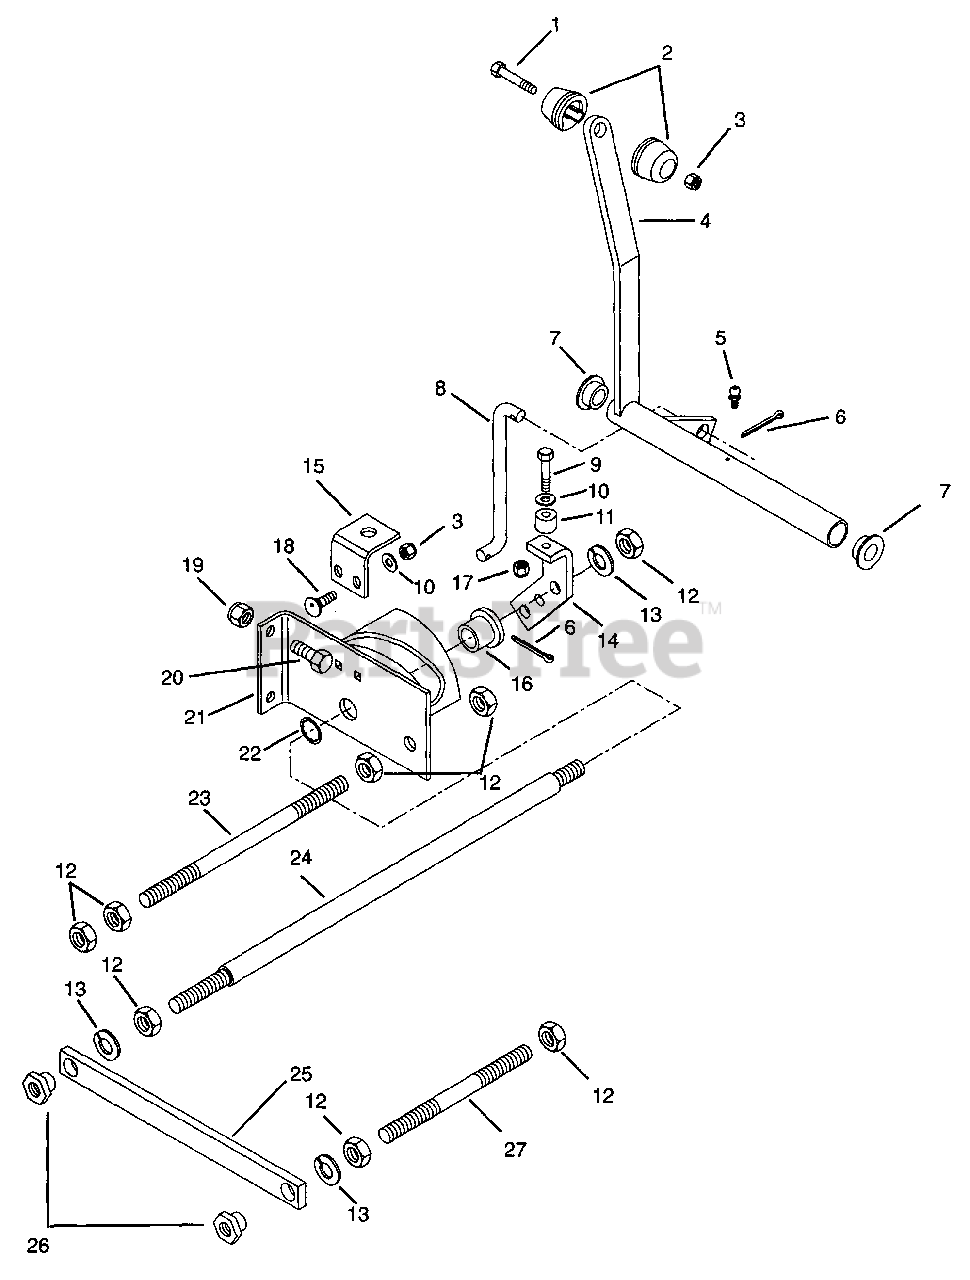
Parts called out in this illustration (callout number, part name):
1	Bolt-Hex .25-20 x 1.50 Grade 5
2	Knob, Control
3	Nut-Locking-Center .25-20
4	Control, PTO
5	Fitting-Lube .25-28 x .256
6	Pin-Center .09 x 1.0
7	Bushing-Flange .515 x .750 x .745 x 1.00
8	Rod, PTO
9	Bolt-Hex .25-20 x 1.25 Grade 5
10	Washer-Flat-Steel .281 x .620 x .065
11	Roller-Clutch Cam .250 x .750 x .5625
12	Nut-Hex .50-13
13	Washer-Lock .500 x .151
14	Arm, PTO Clutch Roller
15	Bracket, Interlock
16	Bearing-Flange 2.00
17	Nut-Locking-Nylon .25-20 Grade 5
18	Bolt-Round Head Square Neck .25-20 x .75 Grade 5
19	Nut-Locking-Center .38-16
20	Bolt-Hex .38-16 x 1.00 Grade 5
21	Weldment, PTO Bracket
22	Ring-Retaining-External 1.31 x .05
23	Rod, Lift
24	Rod, PTO
25	Spring, PTO
26	Bushing-Flange .500 x .875 x .700
27	Stud, PTO
